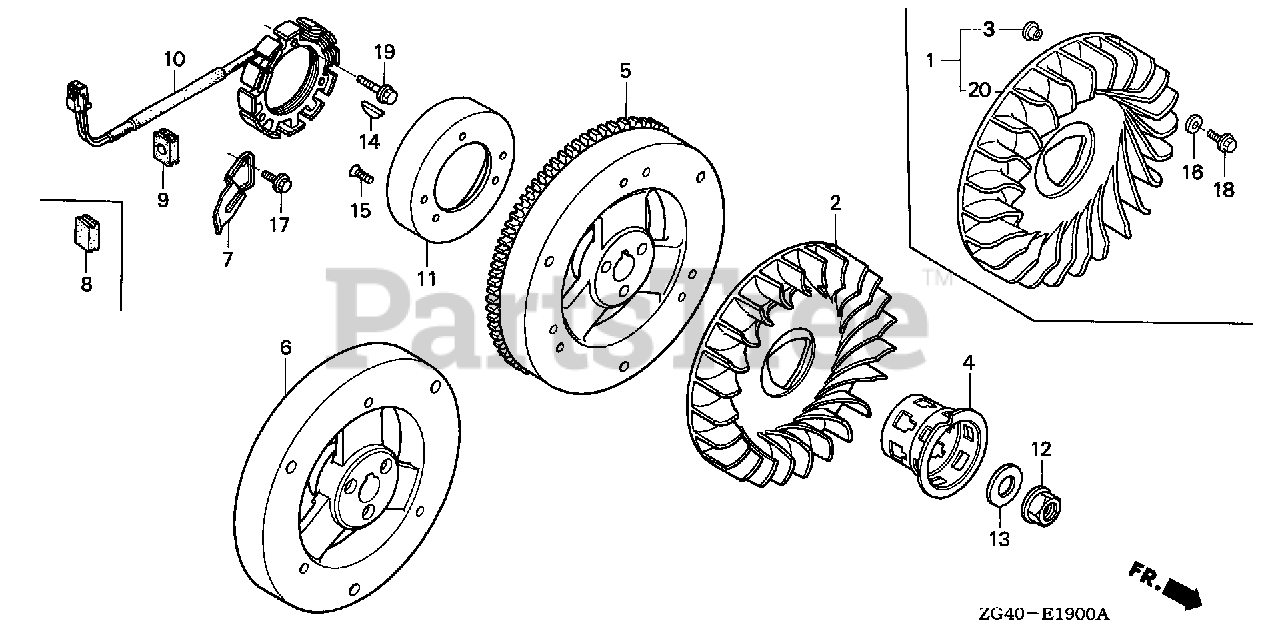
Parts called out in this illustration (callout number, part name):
2	FAN, COOLING
4	PULLEY, STARTER
5	FLYWHEEL (SELF STARTER)
7	CLAMP, WIRE
9	GROMMET, WIRE
10	STATOR (1.7A)
11	ROTOR (4MAGNET)
12	NUT, FLANGE (20MM)
13	WASHER (20MM)
14	KEY, WOODRUFF (50X7)
15	SCREW, FLAT (6X12)
17	BOLT, FLANGE (6X12)
19	BOLT, FLANGE (6X22)
